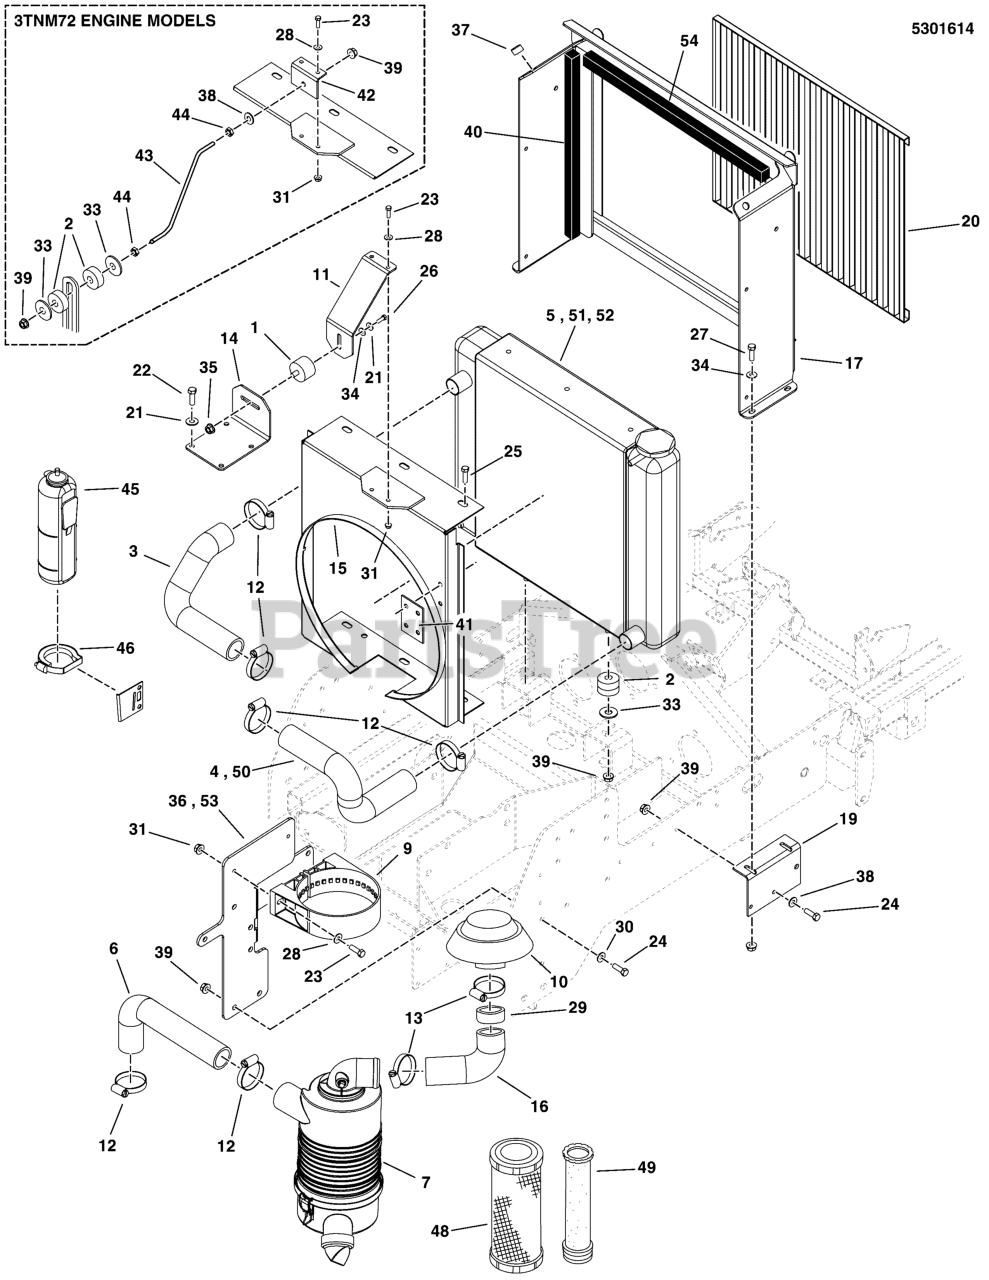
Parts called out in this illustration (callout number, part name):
1	MOUNT,ISO,TOP,RAD 5000Z-DIESEL
2	MOUNT, ISO, BOTTOM, RAD 5000Z-DIESEL
3	HOSE, UPPER, RADIATOR
4	HOSE, LOWER, RADIATOR
5	* RADIATOR I, IS2500
6	HOSE, AIR CLEANER, IS2500Z
6	HOSE, AIR CLEANER, YANMAR
7	AIR CLEANER ASSY
9	BRACKET, AIR CLEANER ASSY
10	CAP, A/C RAIN
11	MOUNT, UPPER RADIATOR
12	CLAMP, SS HOSE, 1-3/4
13	CLAMP, SS HOSE 2-3/4
14	MOUNT, UPPER ENGINE - RED
15	WELD, SHROUD - BLK
16	HOSE, AIR FILTER, IS2500 YANMAR
17	WELD, RADIATOR ENCLOSURE - RED
19	PLATE, MOUNT,RADIATOR ENCLOSURE,LH - RED
20	SCREEN, FRONT, RAD
21	WASHER, 5/16 LOCK CZ
22	BOLT, M8-1.25 X 20MM GD8.8
23	BOLT, 1/4-20 X 3/4 GD5 YZ
24	BOLT, 3/8-16 X 1" GD5 CZ
25	BOLT, 5/16-18 X 1/2 FLANGE, SPEC
26	BOLT, 5/16-18 X 3/4 GD5
27	BOLT, 5/16-18 X 1 GD5 YZ
28	WASHER, 1/4 SAE
29	SLEEVE, 2.0 OD X 1.87 ID X 2.5 LG - BLK
30	WASHER, 3/8 USS
31	NUT, 1/4-20 HEX NYLOCK FLANGE
32	NUT, 5/16-18 HEX NYLOCK FLANGE
33	WASHER-3/8 FENDER
34	WASHER, 5/16" SAE
35	NUT, 5/16-18 HEX SERRATED FLANGE (LARGE)
36	BRACKET, AIR FILTER - RED
37	MNT, VBRTN, RBBR
38	WASHER, 3/8 SAE
39	NUT, 3/8-16 HEX NYLOCK FLANGE
40	FOAM, 3/4 X 1 X 18
41	TAB, MOUNT, COOLANT TANK - BLK
42	BRACKET,RADIATOR TOP SUPPORT,IS2500 -RED
43	ROD, RADIATOR SUPPORT, 24HP YANMAR
44	NUT, 3/8-16 HEX JAM
48	ELEMENT ASSY
49	AIR FILTER ELEMENT, SMALL DIA., INT (SV)
50	HOSE, LOWER, RADIATOR
52	RADIATOR III, IS2500
53	BRACKET, AIR FILTER - RED
54	FOAM, 1/2 X 1 X 18
